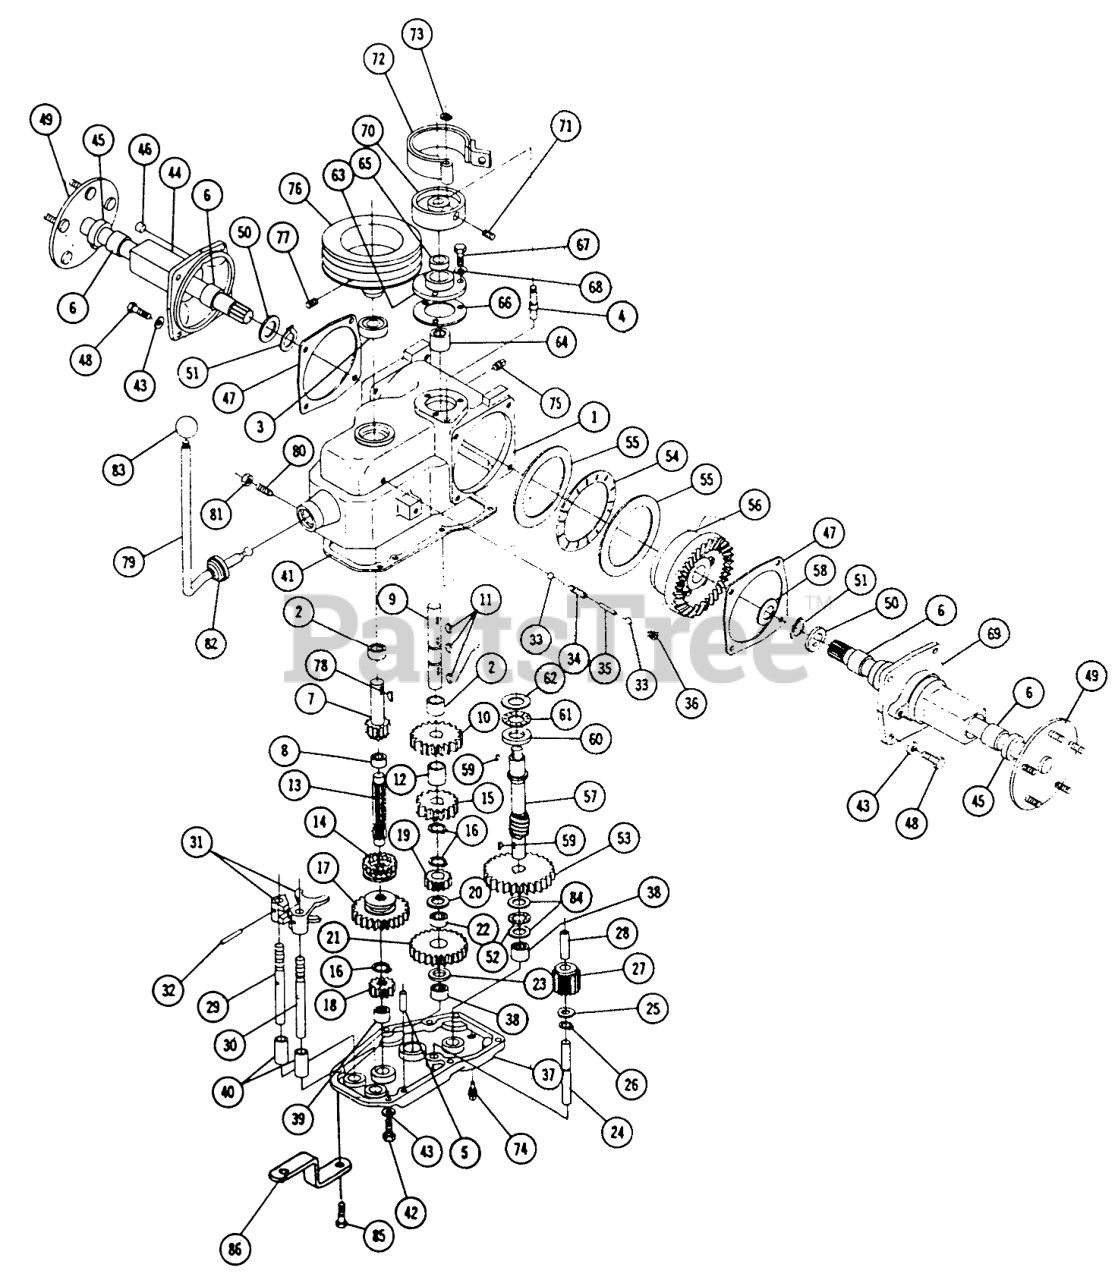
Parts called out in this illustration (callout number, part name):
1	Housing-Gear Case
2	BEARING-NEEDLE
5	PIN-DOWEL
6	BEARING-NEEDLE
8	BEARING-NEEDLE
9	Shaft Idler
18	GEAR
19	Gear-1st Speed
20	WASHER-THRUST
22	BEARING-NEEDLE
24	Shaft-Reverse Idler
25	RACE THRUST
27	GEAR/BUSHING ASM-REVERSE IDLER
28	BUSHING
29	RAIL-SHIFT
30	RAIL-REAR SHIFT
32	PIN-ROLL
33	BALL-DETENT
35	PIN-SHIFT
38	BEARING-NEEDLE
40	Bushing-Shifter Rail
42	Bolt 3/8-16 x 1
43	Lockwasher
48	Bolt 3/8-16 x 1
49	Axle
56	BULLT 325
59	KEY WOODRUFF
62	Rae-Thrust
67	Bolt 5/16-18 x
68	Lockwasher
69	Housing Axle L.H.
71	Screw 1/4-20 x 5/8
74	Plug 1/4 Pipe
77	Set Screw-Nylok
78	Key
80	SETSCREW
81	Nut 1/4-20
85	Bolt 3/8-16 x 1
